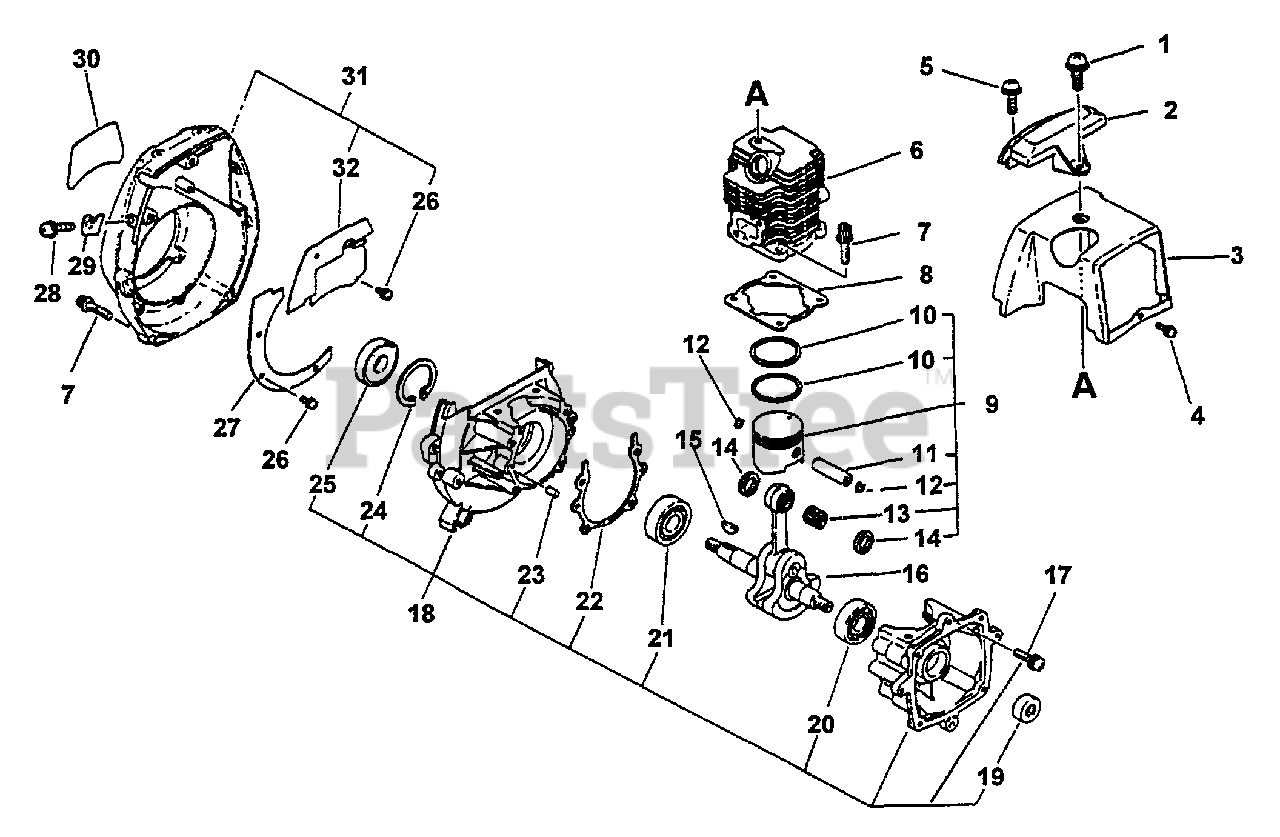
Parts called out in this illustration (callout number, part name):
1	SCREW - 5X16
2	GUARD - TOP
3	COVER, ENGINE
4	SCREW - 4X10
5	SCREW - 4X14
6	CYLINDER
7	SCREW - 5X20
8	GASKET, CYLINDER
9	PISTON KIT
10	RING, PISTON
11	PIN, PISTON
12	RING, RETAINING
13	BEARING, NEEDLE
14	SPACER, PISTON
16	CRANKSHAFT ASSY
17	SCREW - 5X25
18	CRANKCASE KIT
19	SEAL, OIL
20	BEARING, BALL - 6001C3
21	BEARING, BALL - 6201
22	GASKET, CRANKCASE
23	PIN - LOCATING
24	RING, RETAINING - 32
25	SEAL, OIL
26	SCREW - 4X8
27	SHIELD, FAN
28	SCREW - 4X10
29	HOLDER, CABLE
30	LABEL - MODEL SRM-2501S
31	FAN CASE ASSY
32	SHIELD, FAN
